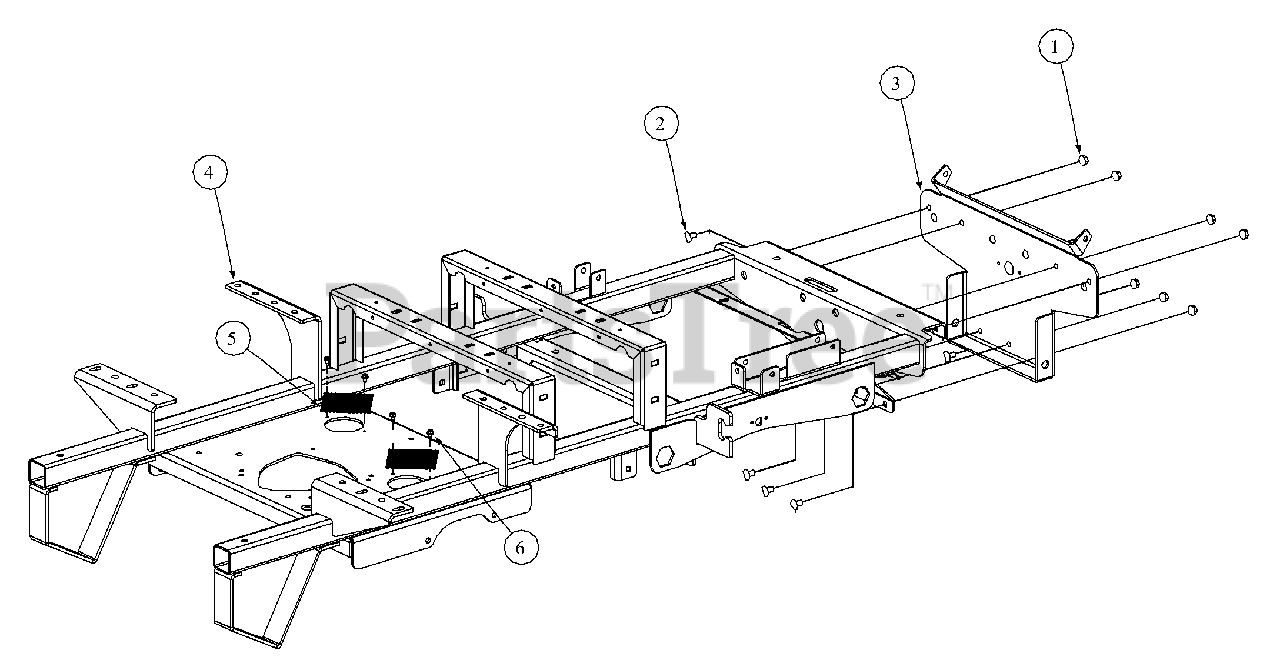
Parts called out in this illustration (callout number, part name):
1	Hex Nut, 3/8-16 Flange Lock
2	Carriage Bolt, 3/8-16 x .75 Long
3	Bracket Assembly, Frame, Front
4	Frame Assembly
5	Cover, Hydro Fan
6	Screw, TT, 1/4-20 x 0.5
